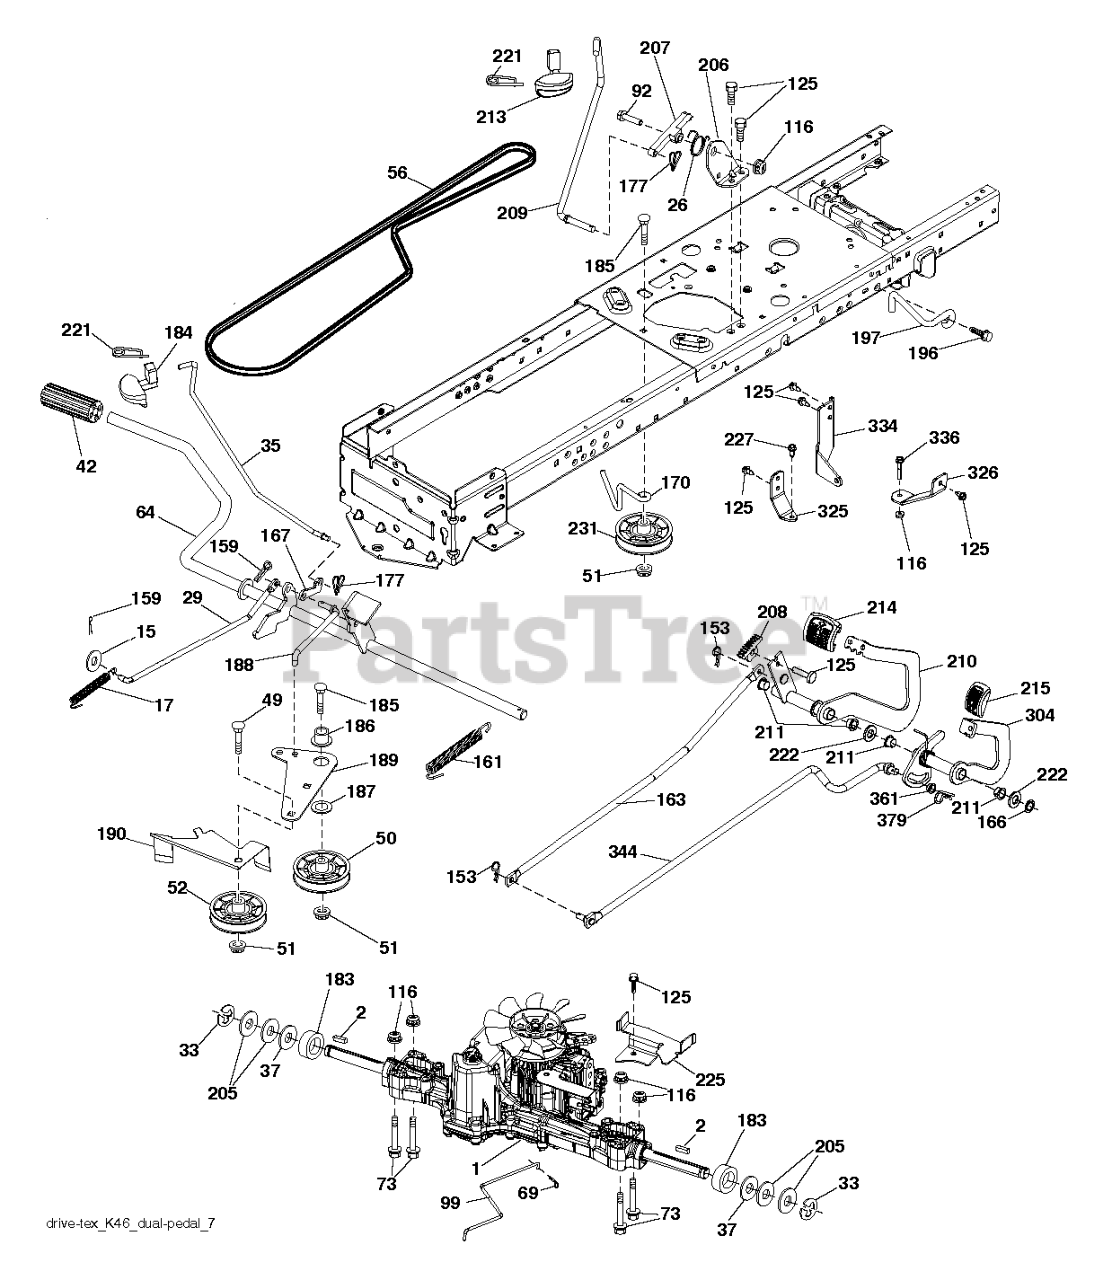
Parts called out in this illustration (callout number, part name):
2	SQUARE KEY
15	WASHER PLAIN WASHER 3/8 X 0.08
17	SPRING.BRAKE.K46.GREEN
26	SPRING.RETURN.CRUISE
29	ROD.BRAKE.K46
35	ROD ROD.PARKINGBRAKE.GT.HUSQ/P
37	WASHER.HARDENED
42	PEDAL COVER
50	IDLER.FLAT.910.OFFSET
51	NUT LOCK FLG 3/8-16 UNC
52	IDLER.V-GROOVE.910.OFFSET
64	SHAFT.ASM.PEDAL.BRK.CNTR
69	HAIRPIN.SOFT.ZINC.059X1.125
99	ARM.PIVOTING.TCRD.GEN2.5.BAGGE
125	SCREW
153	RETAINER M
161	SPRING, RETURN LT
166	NUT.PUSH.625
167	LATCH.BRAKE.SPRING
170	KEEPER.CENTER SPAN.1.688
177	PIN COTTER;LOCKING;BOWTIE;1IN
183	SPACER AXLE
184	HANDLE.PARKING.BRAKE.H (BLK)
186	SPACER.RETAINER
188	LINK.CLUTCH.GROUND DRIVE.LONG
189	BELLCRANK.GROUND.DRIVE.TEX.
190	KEEPER.BELLCRANK.DRIVE
196	SCREW 3/8-16X1
197	BRKT.42.FCS.CLUTCH.ANTIROTATIO
206	BRACKET.MOUNT.CRUISE.LATCH
209	ROD ROD.CRUISECONTROL.GT.HUSQ/
211	BEARING.NYLON
213	KNOB.CONTROL.CRUSIE.HU
214	PEDAL.FORWARD.PAD.TEX
221	RETAINER.SPRING.CLIP.H
222	WASHER 21/32 X 1-1/4 X 10 GA.
225	KEEPER.BELT.TRANSAXLE.K46
231	IDLER.V-GROOVE.1.688.OFFSET
325	TORQUE.STRAP.K46.LT.LH
326	BRCKT.PNT.TRQ.STP.46.18TIRE.RH
334	SWAY.ROD.BRACKET.K46.X431
